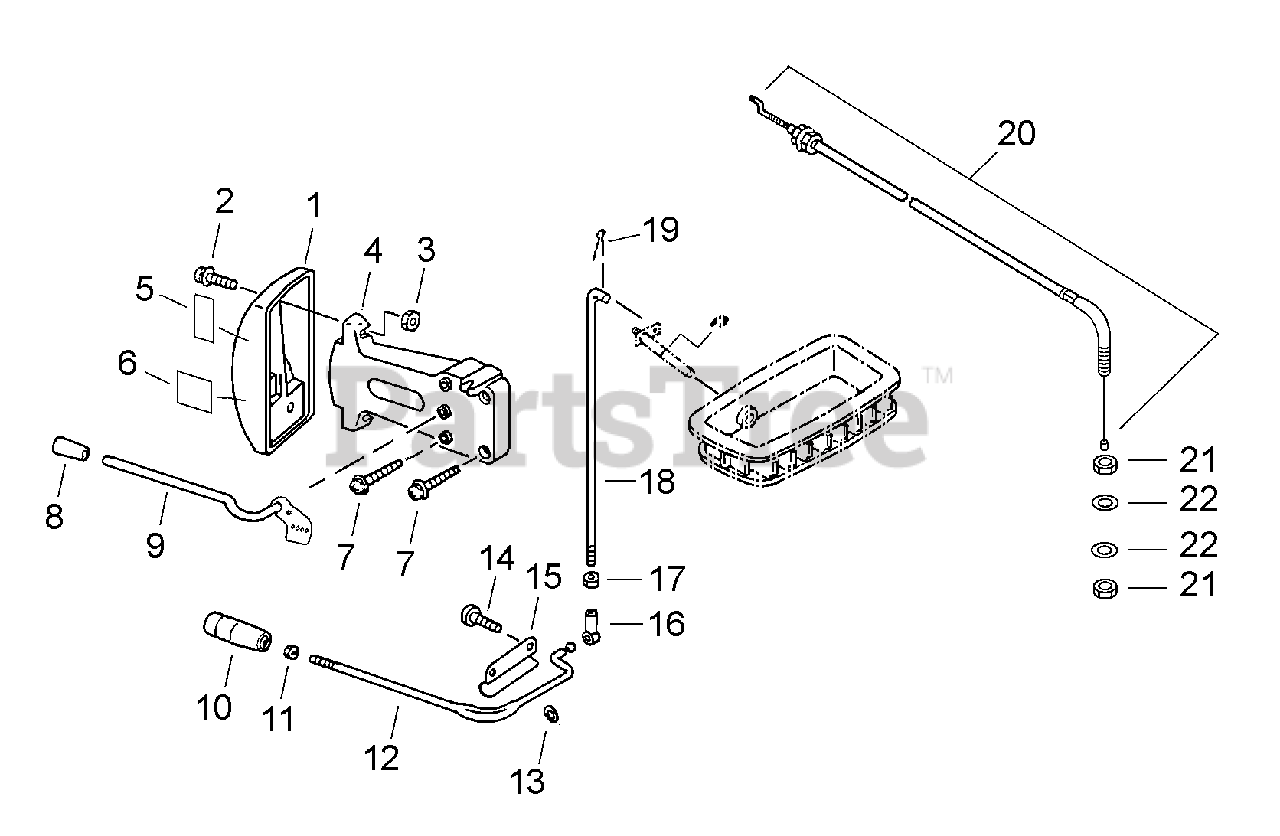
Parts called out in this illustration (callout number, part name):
1	DIAL, RATE CONTROL
2	SCREW - 5X25
4	BRACKET, DIAL
5	LABEL - THROTTLE
6	LABEL - STOP
7	SCREW - 5X25
8	KNOB
9	LEVER, THROTTLE CONTROL
12	LEVER, SHUTTER CONTROL
13	WASHER - 8
14	SCREW - 5X14
15	BRACKET, LEVER
16	CONNECTOR
18	ROD, CONTROL LEVER
19	PIN, SPLIT - 1.8×18
20	CABLE, THROTTLE
22	WASHER - 6
